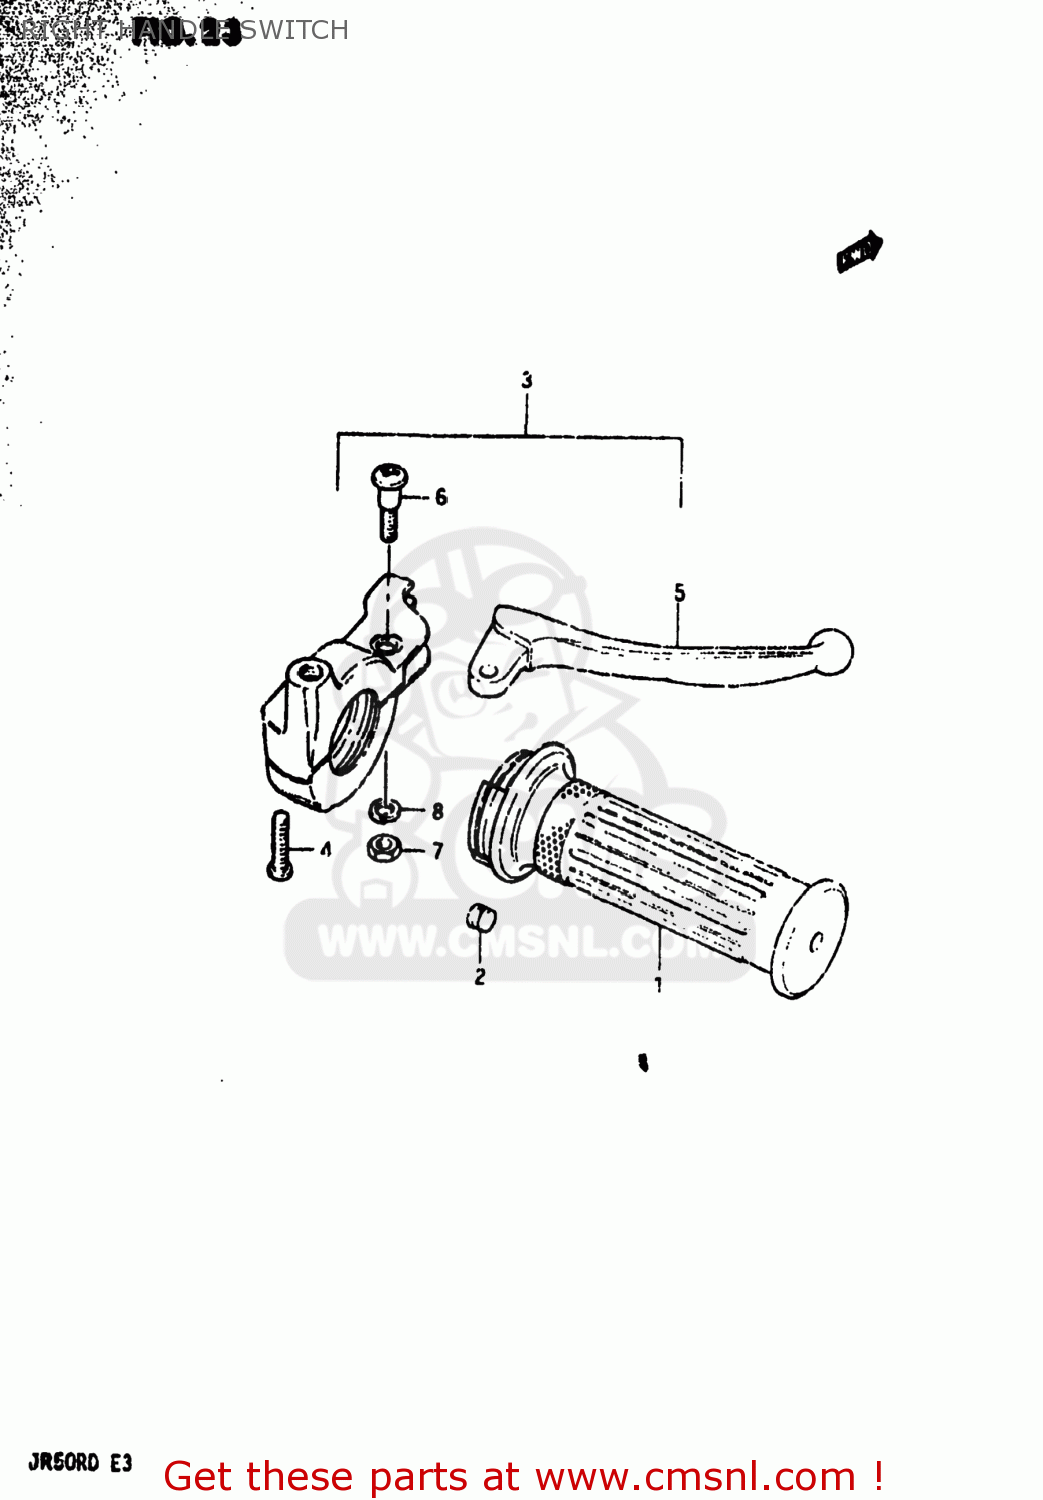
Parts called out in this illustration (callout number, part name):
1	GRIP,THROTTLE
2	PIECE,THROTTLE END
3	LEVER ASSY,BRAKE
4	SCREW
5	LEVER,BRAKE
6	SCREW
7	NUT
8	LOCK WASHER
